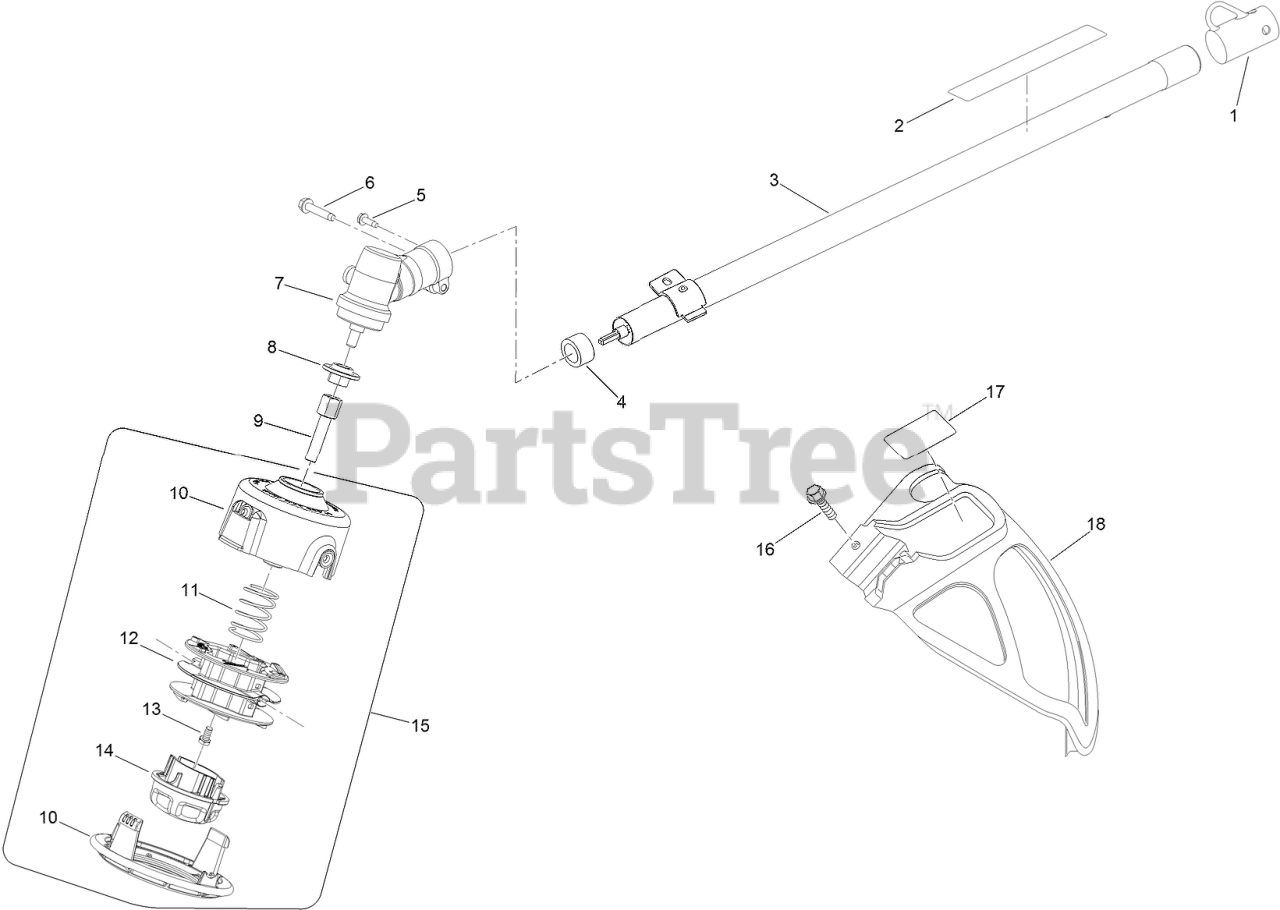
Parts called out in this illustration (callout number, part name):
1	CAP-HANGER
2	DECAL-LABEL, WARNING
3	STRAIGHT SHAFT ASM
5	SCREW-HWH
7	GEAR CASE ASM
8	WASHER-FLANGE
9	ADAPTOR-HEAD SHAFT, TRIMMER
10	HOUSING-SPOOL, STRAIGHT SHAFT
11	SPRING-COMPRESSION
12	SPOOL
14	KNOB-BUMP
15	TRIMMER HEAD ASM
16	SCREW-HWH
17	LABEL-DEFLECTOR, GRASS
18	GRASS DEFLECTOR ASM
